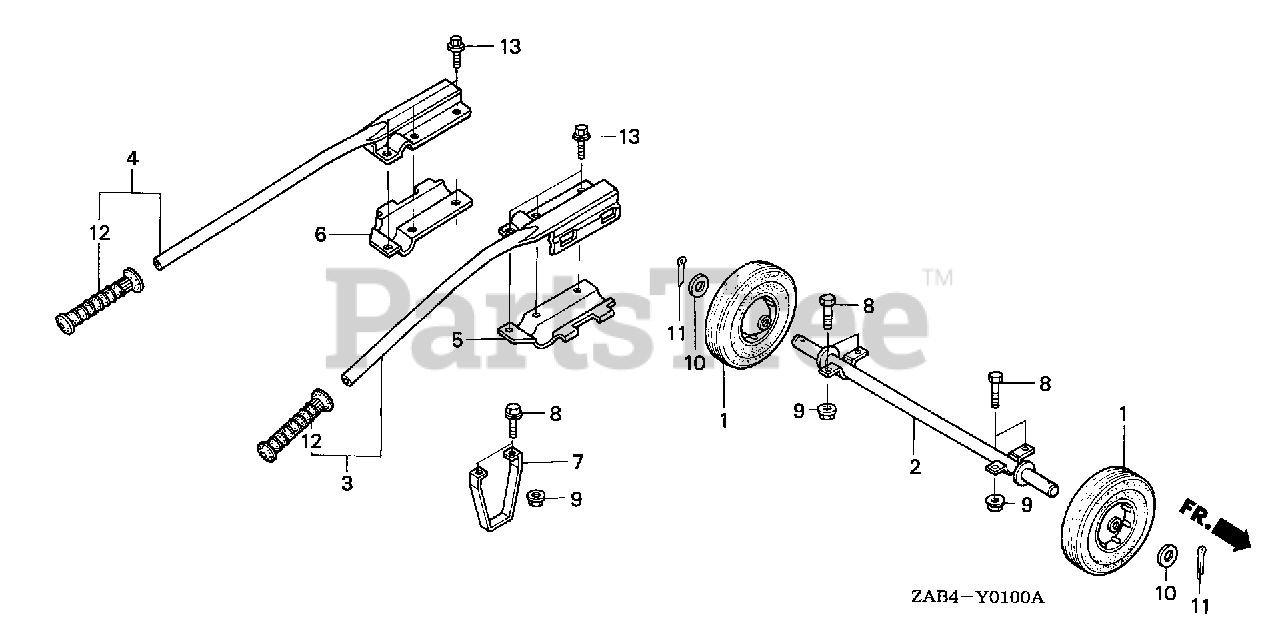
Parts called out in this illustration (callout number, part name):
1	WHEEL (10"X2.75")
2	SHAFT, WHEEL
3	HANDLE, R. (LOWER)
4	HANDLE, L. (LOWER)
5	BRACKET, R. HANDLE (UPPER)
6	BRACKET, L. HANDLE (UPPER)
8	BOLT, HEX. (8X16)
9	NUT, FLANGE (8MM)
10	WASHER, FLAT (20MM)
11	PIN, COTTER (4.0X30)
12	GRIP, R. HANDLEBAR
13	BOLT, FLANGE (8X16)
